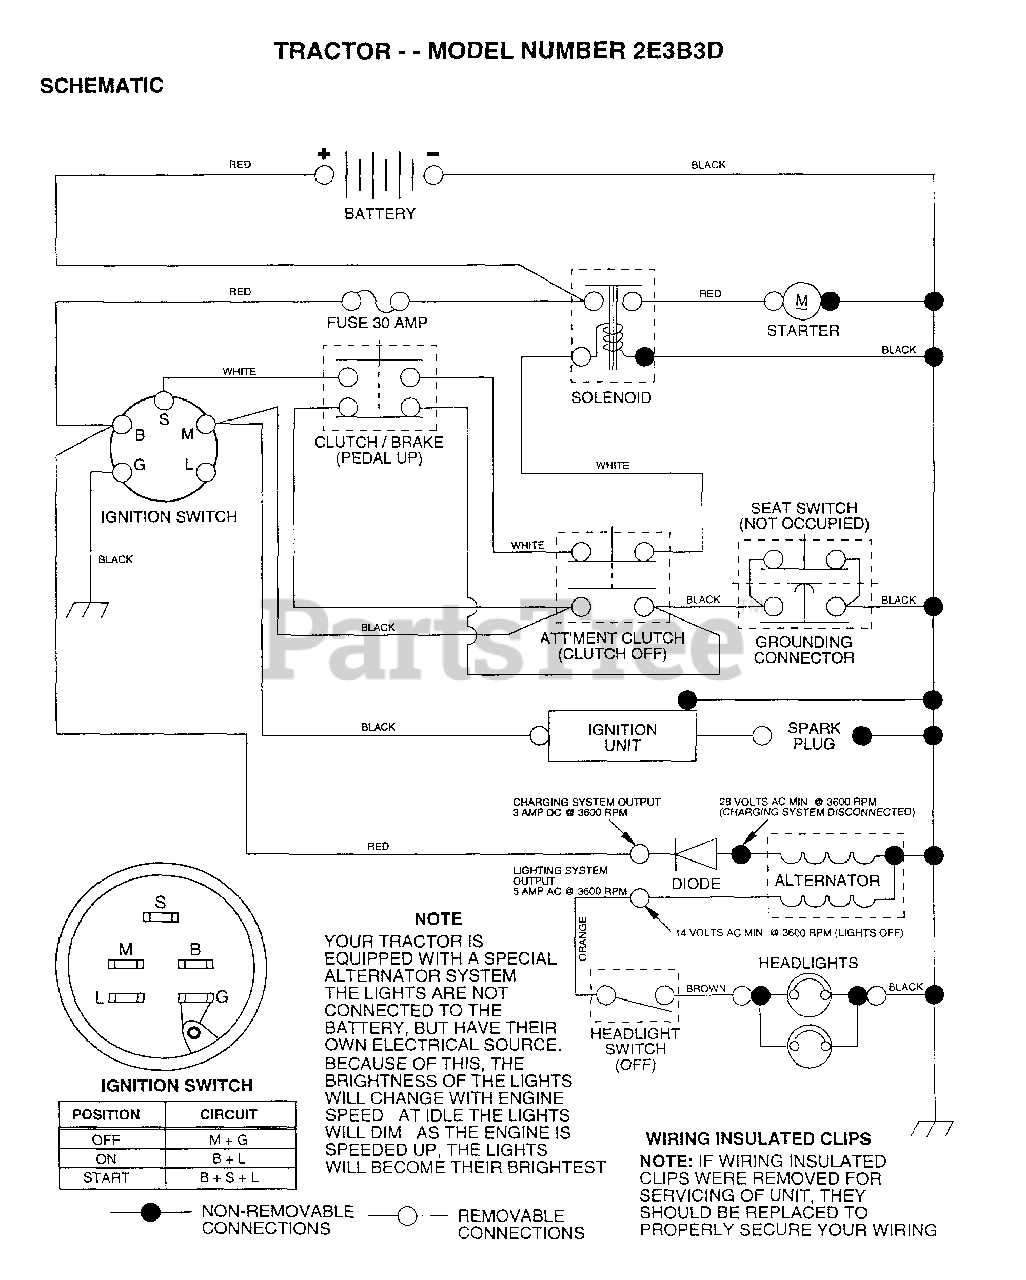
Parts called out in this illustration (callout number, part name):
2	BOLT LT
3	WASHER
4	LOCKWASHER
7	TUBE T
9	HOSE CLAMP T
15	FASTNER.SNAP-IN
16	SWITCH INTERLOCK
20	NUT
21	"HARNESS,LIGHT SOC"
22	HEADLAMP BULB
24	"CABLE T, BATTERY"
25	CABLE.BTRY.6GA.RD
26	FUSE HYT
28	CABLE T
29	SWITCH SEAT
32	COVER KEY SWITCH
33	KEY MLD GEN DELTA
34	SWITCH LT
36	SCREW
38	BRACKET SWITCH IN
39	SWITCH INTERLOCKT
40	HARNESS.IGN.DASH.
41	BOLT HXHD FIN
44	NUT HXKEP 1/4X20
45	ADAPTER AMMETER
49	WASHER PINNED
70	HARNESS ENG DUAL
